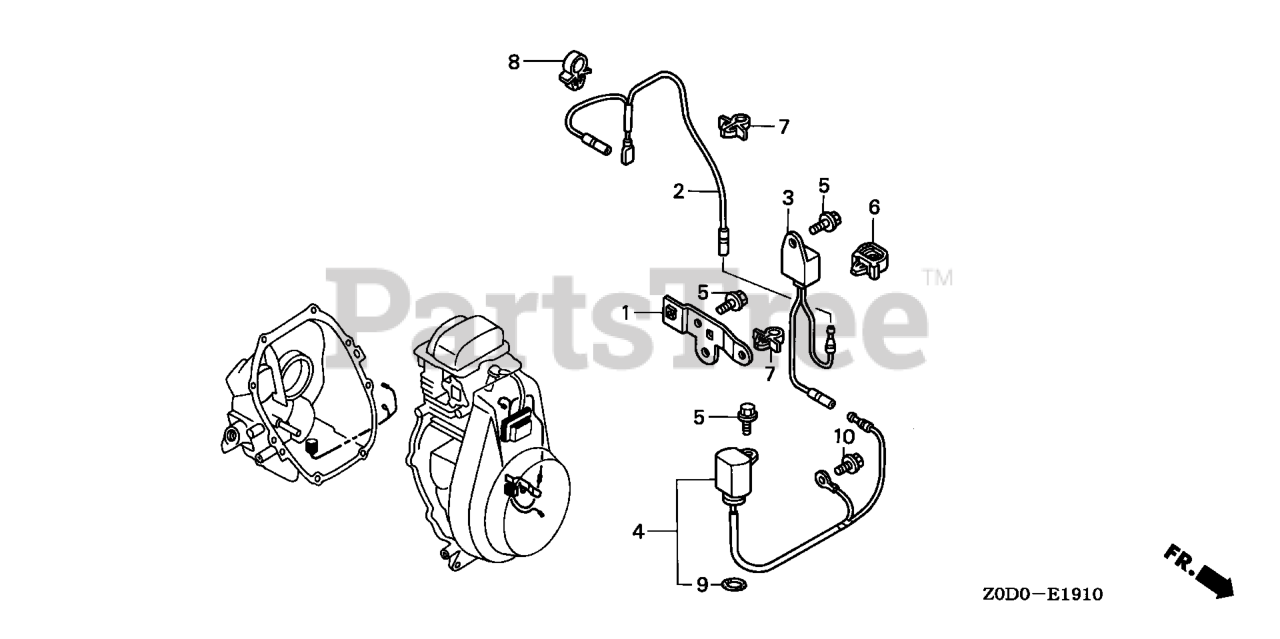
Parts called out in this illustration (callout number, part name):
1	BRACKET, OIL ALERT UNIT
2	WIRE, STOP SWITCH
3	ALERT UNIT, OIL
4	SWITCH ASSY., OIL LEVEL
5	BOLT, FLANGE (6X14)
6	CLIP, WIRE HARNESS (10MM)
7	CLIP, CABLE (A)
8	CLIP B, CABLE
9	O-RING (11.8X2.4)
10	BOLT, FLANGE (6X8)
